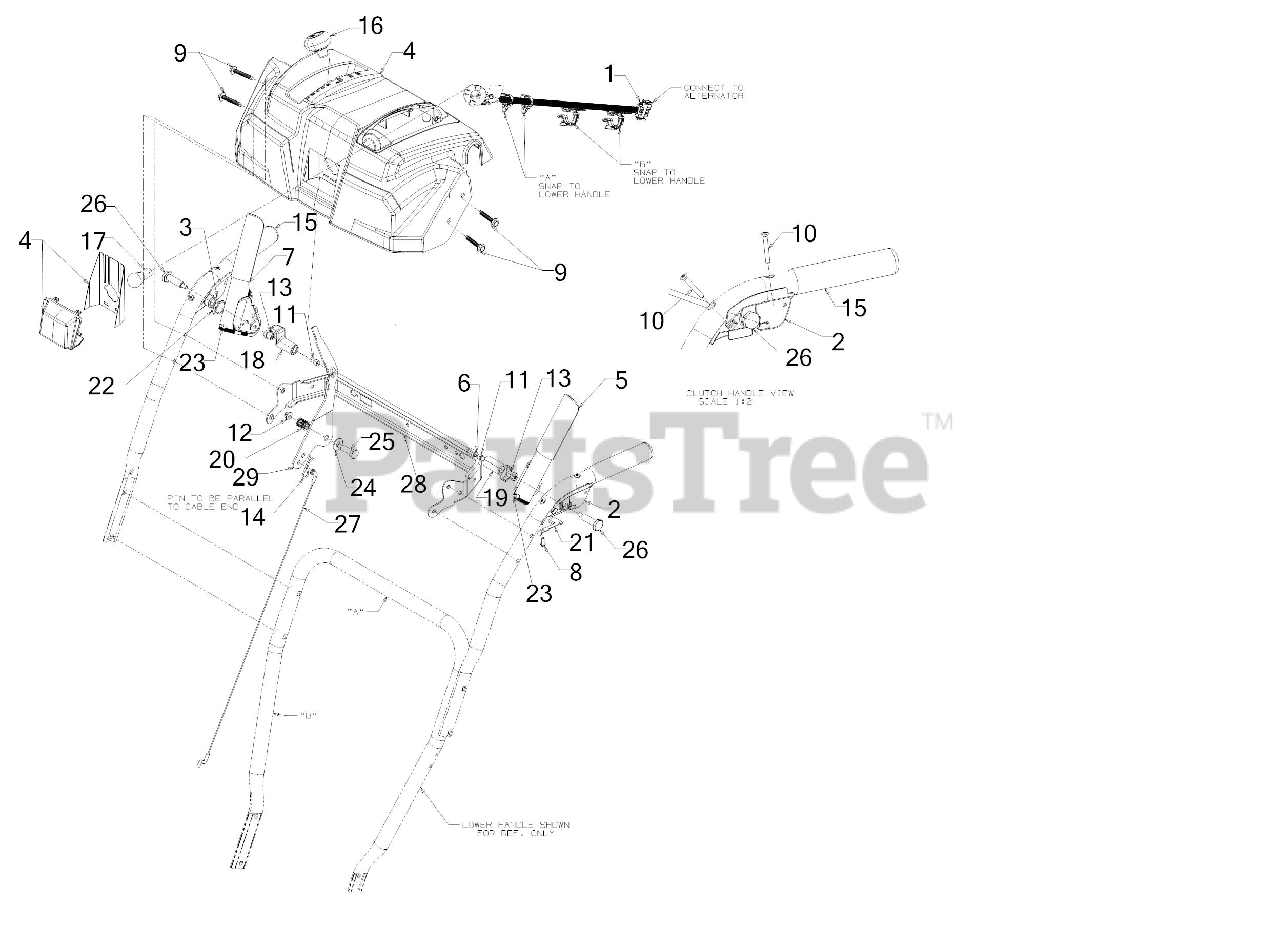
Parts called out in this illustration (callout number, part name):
1	LIGHT HARNESS
1	HEADLIGHT SOCKET
2	CLUTCH LOCK HANDLE ASSEMBLY (LH)
3	CLUTCH LOCK HANDLE ASSEMBLY (RH)
4	HANDLE PANEL ASSEMBLY (TROY-BILT)
5	HANDLE ASSEMBLY (LH)
7	ENGAGEMENT HANDLE ASSEMBLY (RH) (BLACK)
8	SCREW #8-16 x .50
9	SCREW 1/4-20 x 1.625
10	SCREW #10-24 x 1.375
11	SCREW 1/4-20 x .50
12	FLANGE LOCK NUT
13	HEX NUT W/PATCH
14	INTERNAL COTTER PIN
16	SHIFT KNOB
17	LAMP-#1683
19	CLUTCH LOCK CAM
20	COMPRESSION SPRING
21	CLUTCH SPRING
22	TORSION SPRING
23	RUBBER BUMPER
24	FLAT WASHER
25	SHOULDER SCREW
26	SHOULDER SCREW .437 x 1.345 1/4-20
27	SPEED SELECTOR CABLE (PLASTIC)
